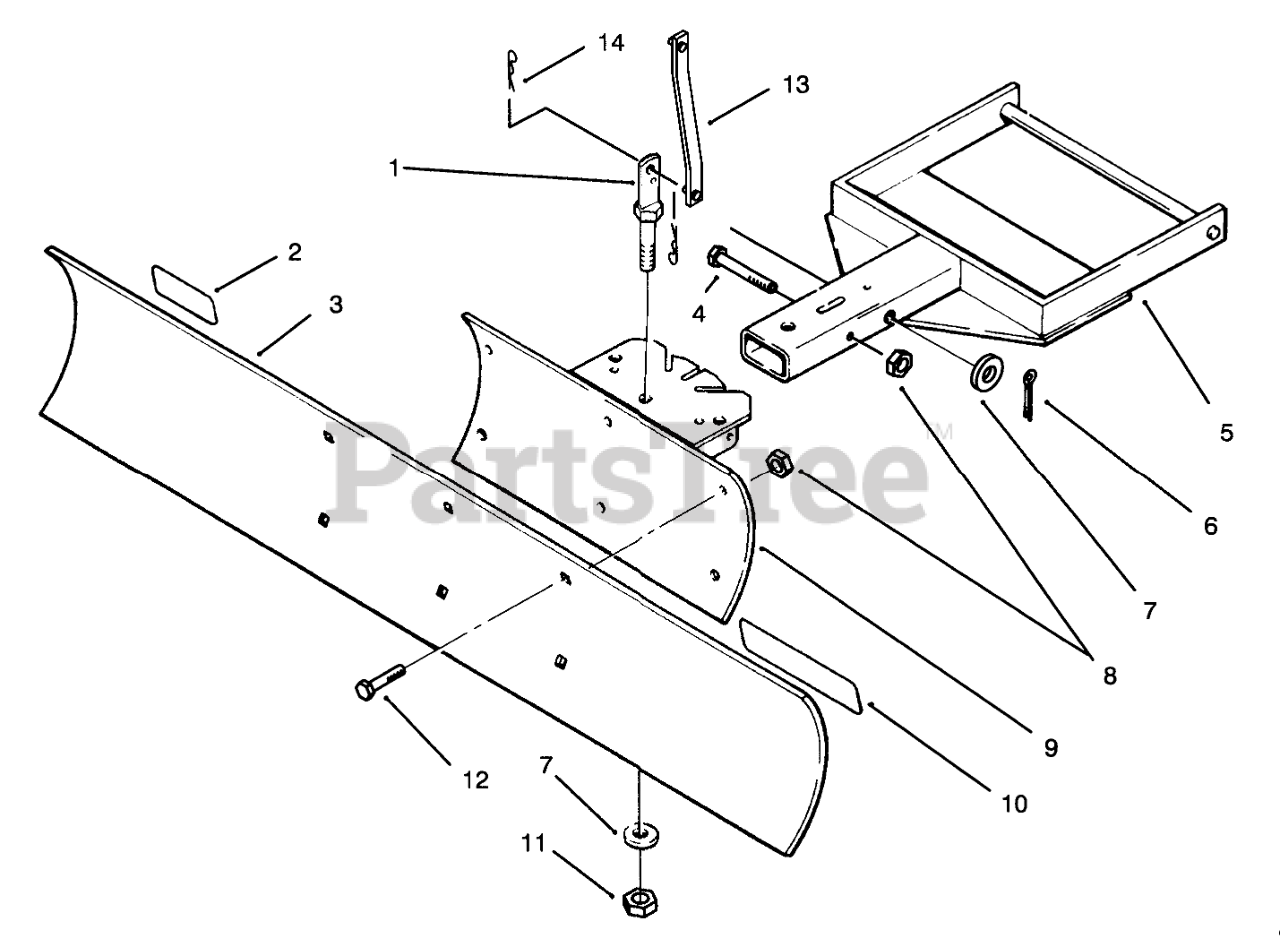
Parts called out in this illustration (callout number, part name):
1	Wa-Scrw
2	DECAL-DANGER
3	Blade (Incl.Ref.#2)
4	SCREW-HH
5	ASS'Y-FRAME R
6	PIN-COTTER
7	WASHER-FLAT
8	NUT-LOCK, NI
9	ASS'Y-QUADRANT
10	DECAL-ATTACHMENT
11	NUT-LOCK
12	BOLT-CARR
13	LIFT BAR WA R
14	Hairpin
